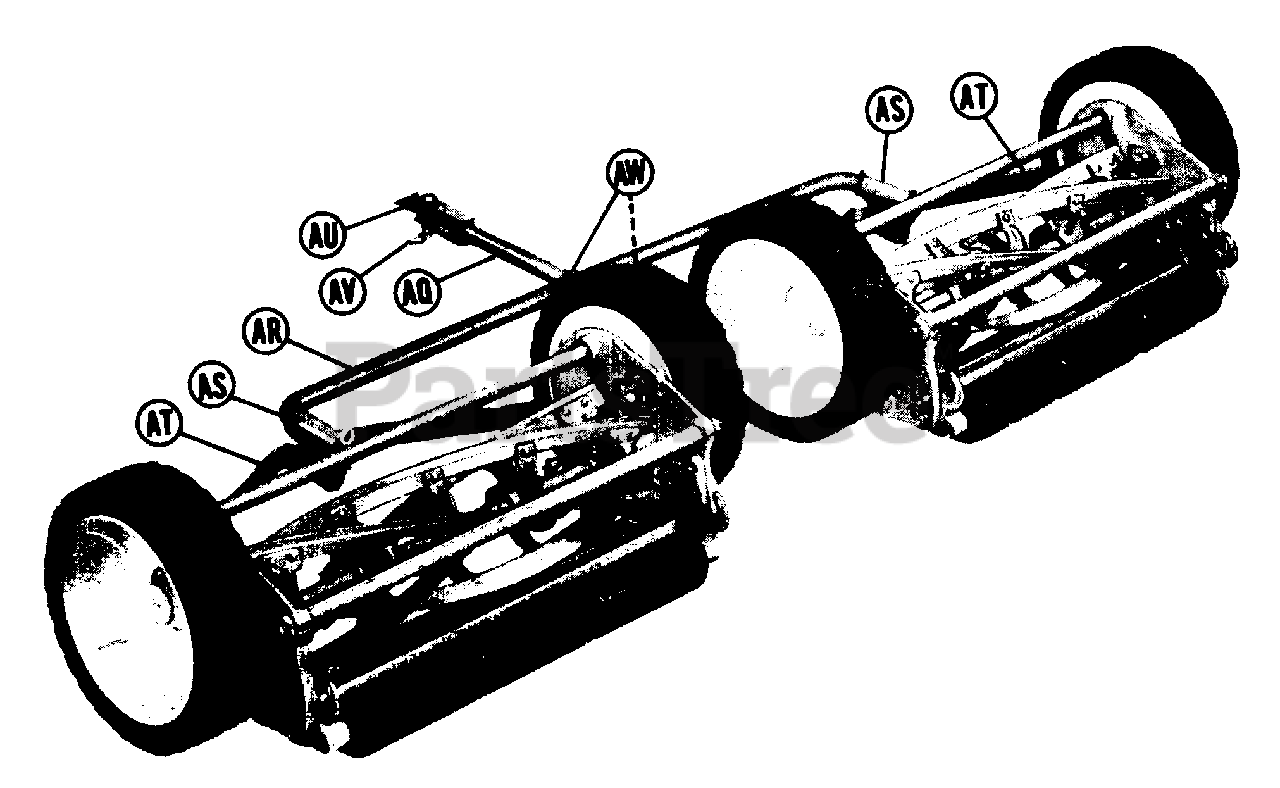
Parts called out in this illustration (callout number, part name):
AQ	Tongue Assembly
AR	Bar, Draw Assembly, Double
AS	Pivot Assembly, Draw Bar
AT	bar Draw, Single
AU	Pin Tongue
AV	Clip, Spring
AW	Collar, Set
